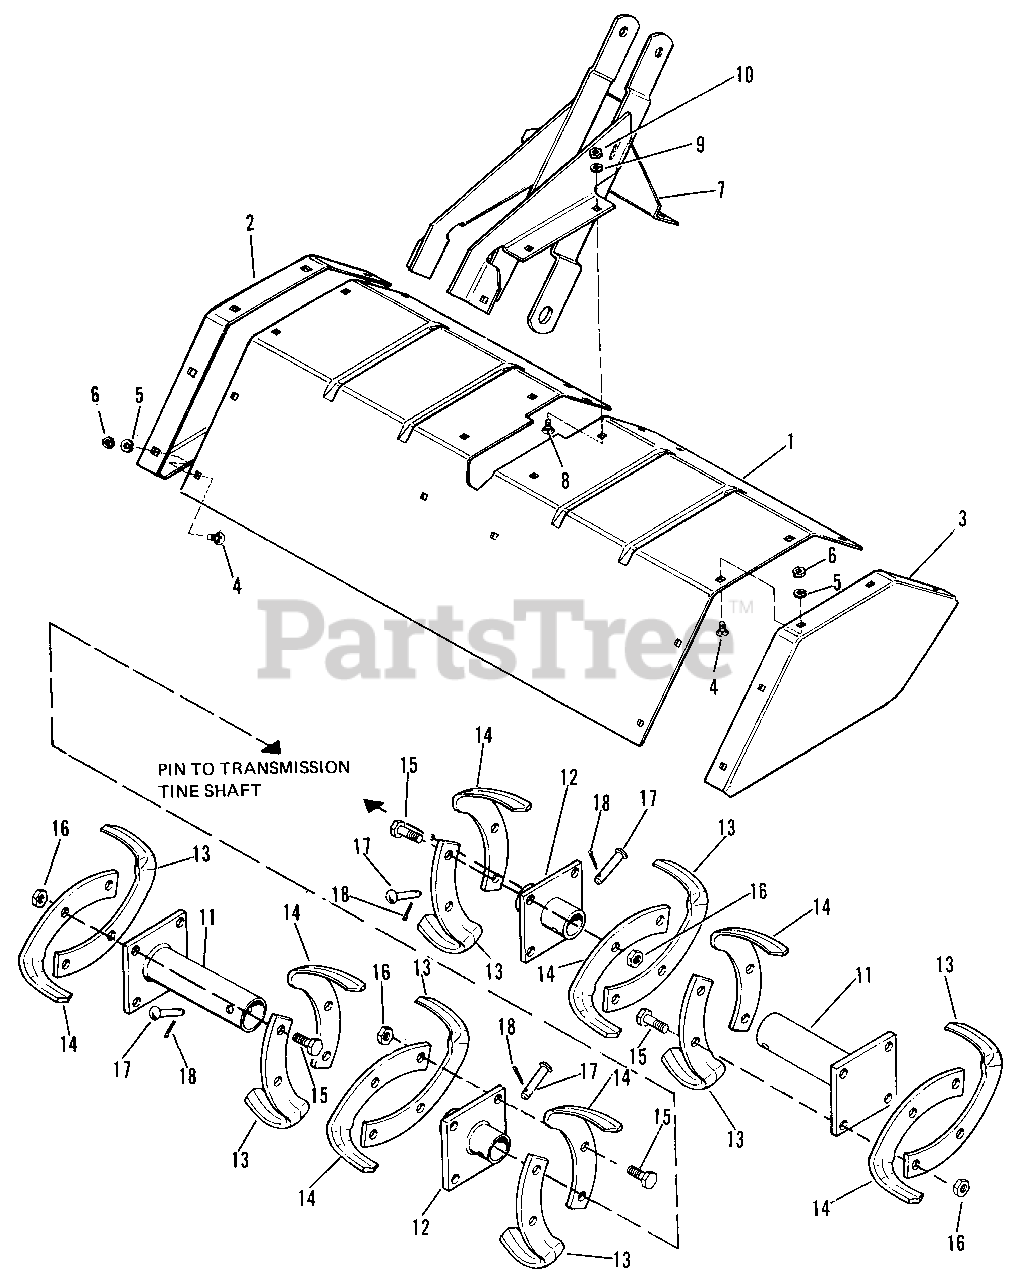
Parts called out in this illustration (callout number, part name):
1	Deflector
2	End Plate Deflector L.H.
3	End Plate Deflector R.H.
4	Bolt Carriage, 5/16"-18 x 1
5	Lock Washer, 5/16"
6	Full Hex. Nut, 5/16"-18
7	Support Assembly
8	Bolt Carriage, 5/16"-18 x 3/4"
9	Lock Washer, 5/16"
10	Full Hex. Nut, 5/16"-18
11	Tine Hub Assembly
12	Inner Tine Plate Assembly
13	Tine Blade L.H.
14	Tine Blade R.H.
15	Hex Cap Screw, 7/16"-20 x 1-1/4" lg.
16	Full Hex. Lock Nut, 7/16"-20
17	Pin
18	Cotter Pin, 1/8" x 3/4"
